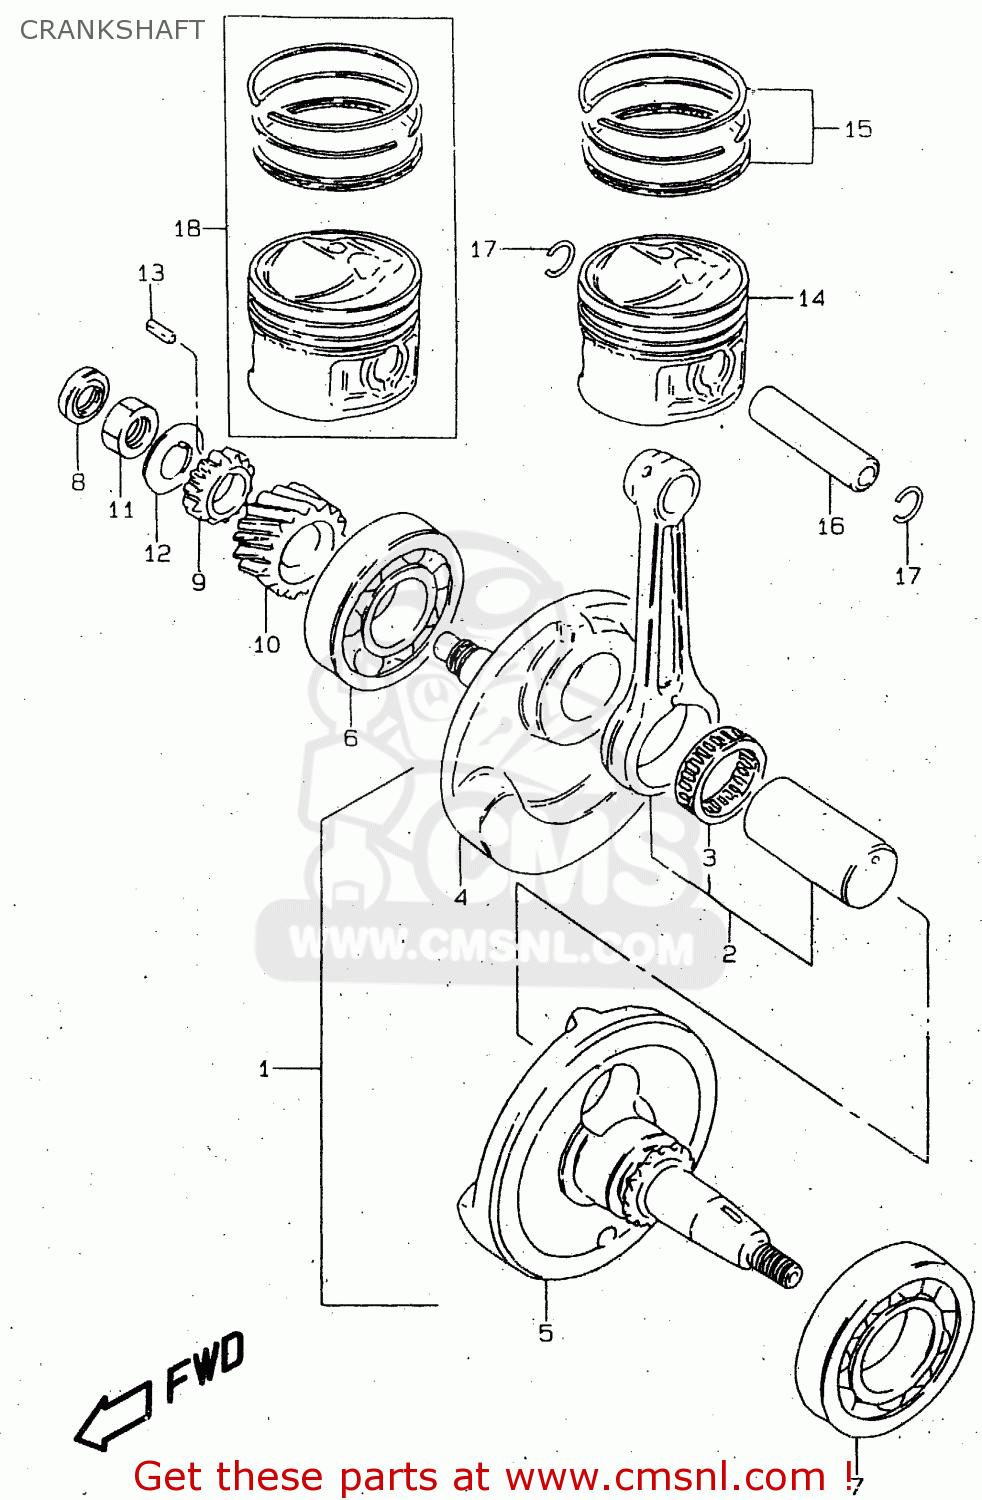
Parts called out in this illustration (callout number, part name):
1	CRANKSHAFT ASSY
2	CONNECTING ROD SET
3	BEARING(28X36X15.8)
4	CRANKSHAFT,R
5	CRANKSHAFT,L
6	BEARING(28X68X18)
7	BEARING(35X72X17)
8	SEAL,OIL(12X21X7)
9	GEAR,OIL PUMP DRIVE
10	GEAR,PRIMARY DRIVE
11	NUT
12	WASHER
13	KEY
14	PISTON
15	RING SET,PISTON
16	PIN,PISTON
17	RING,SNAP 14MM
18	PISTON SET(OS:0.5)
